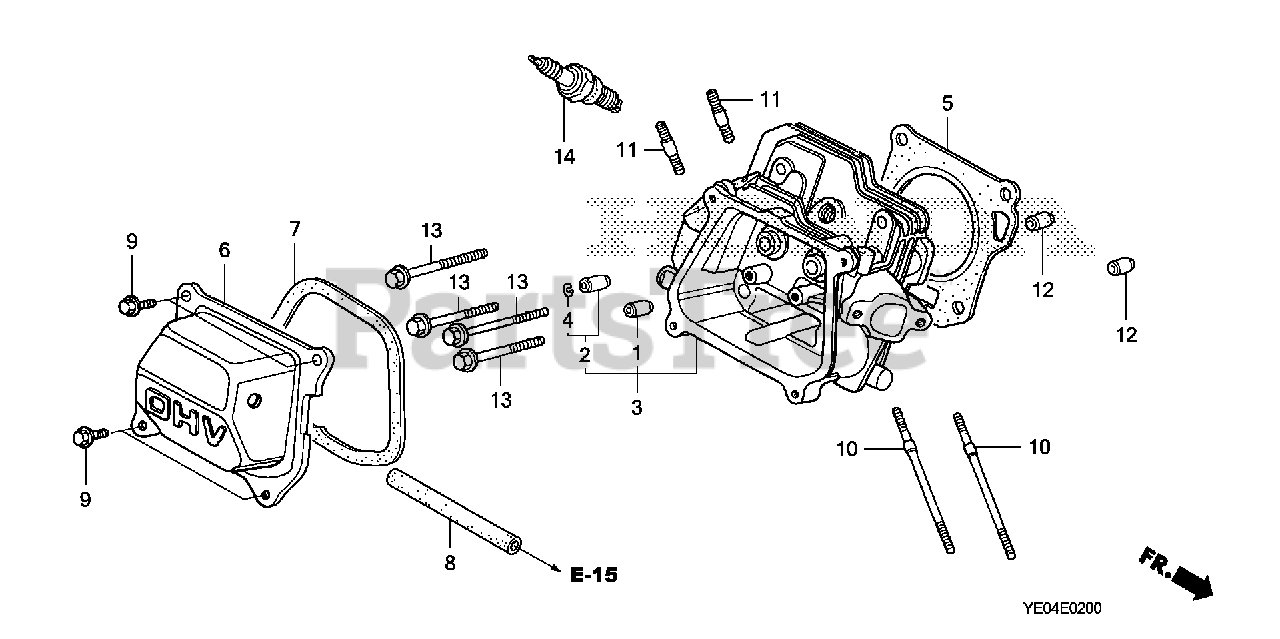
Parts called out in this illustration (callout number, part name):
1	GUIDE, VALVE (OVER SIZE) Use from Engine SN 6324986.
2	GUIDE, EX. VALVE (OS)
3	CYLINDER HEAD
4	CLIP, VALVE GUIDE Use from Engine SN 1231803.
5	GASKET, CYLINDER HEAD (NIPPON LEAKLESS)
6	COVER, HEAD
7	GASKET, CYLINDER HEAD COVER
8	TUBE, BREATHER
9	BOLT, FLANGE (6X12) (CT200)
10	BOLT, STUD (6X109)
11	BOLT, STUD (8X32)
12	PIN A, DOWEL (10X16)
13	BOLT, FLANGE (8X60)
14	SPARK PLUG (BPR5ES) (NGK)
14	SPARK PLUG (BPR6ES) (NGK)
